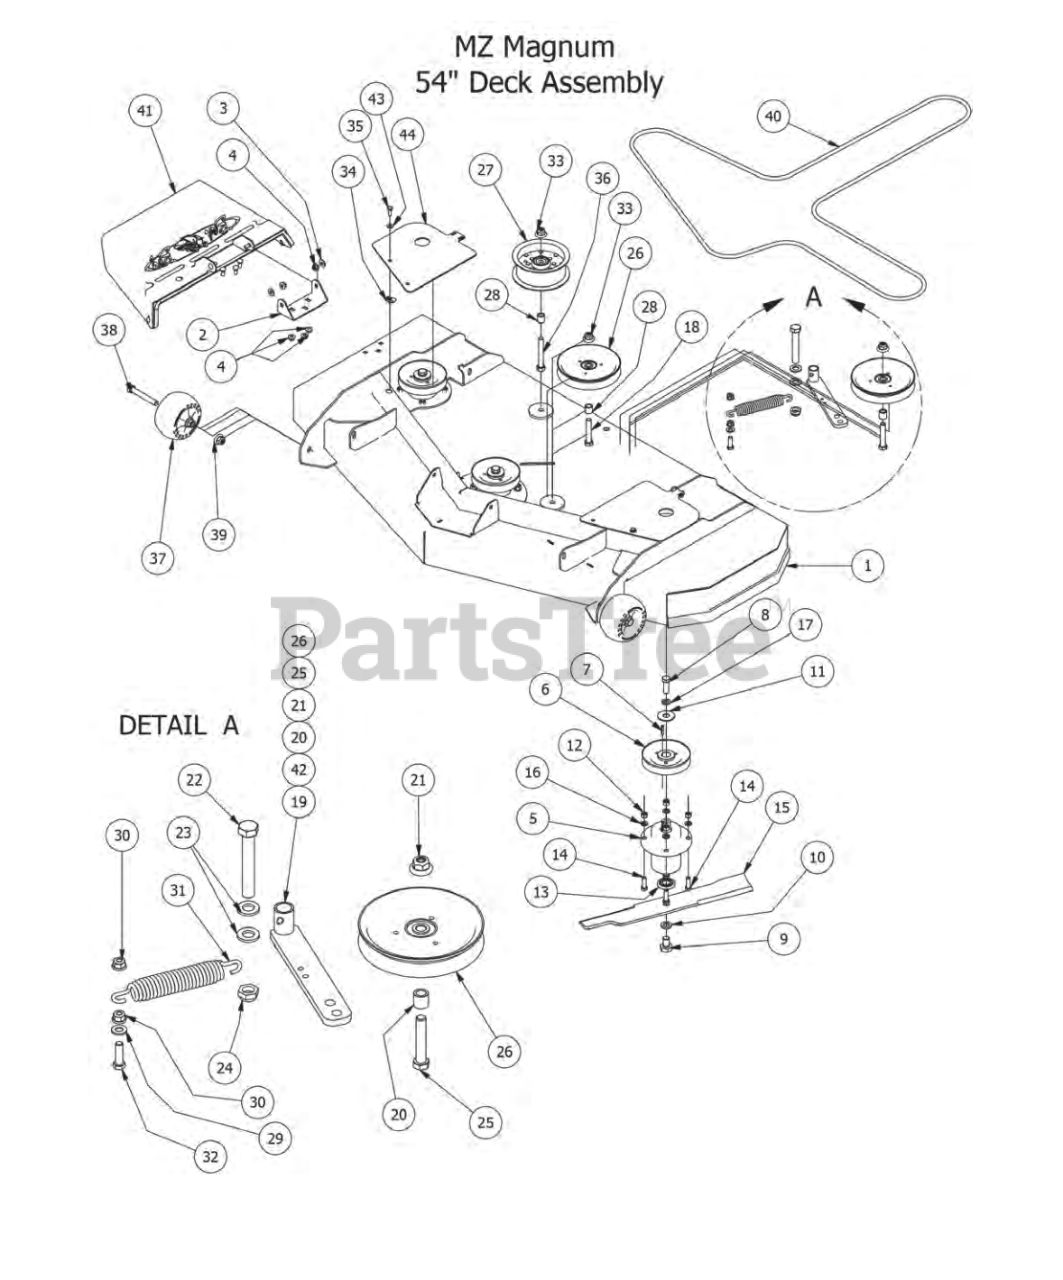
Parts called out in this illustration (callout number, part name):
1	54 MZ Deck
2	Chute Hanger 48 MZ
3	360 ID Plastic Washer
4	5/16" Nylon Flange Nut
6	MZ Deck Pulley
7	3/16 x 1 Square Key
8	1/2"-20 x 1 1/2 Grade 5 Fine Thread Bolt
9	5/8" x 1 1/2" Gr8 Hex Bolt (Fine)
10	5/8" Lock Washer
11	Type B Plain Washer
12	3/8" Hex Nut
13	Spindle Bearing
14	3/8" x 1 1/4" Hex Bolt
15	54" MZ Fusion Blade
16	3/8" Lock Washer
17	1/2" Lock Washer
18	1/2" x 2 3/4" Hex Bolt
19	Deck Idler 2009 AOS
20	3/4 OD x 1/2 ID x 3\4 Length
21	1/2-13 Nylon Flange Nut-Orange
22	5/8" x 4" Hex Bolt
23	.635 ID Plastic Washer
24	5/8-11 Nylon Insert Jam Half Nut
25	1/2" x 2 3/4" Hex Bolt
26	5-3/4 Idler Pulley
27	5 3/4 flat idler-32fI-92-008
28	3/4 OD x 1/2 ID x 3\4 Length
29	3/8" Flat Washer
30	3/8" Nylock Flange Nut
31	Deck Idler Spring 2009
32	3/8" x 1 1/4" Hex Bolt
33	1/2-13 Nylon Flange Nut-Orange
34	1/4-20 Cage Nut
35	1/4" Hex Bolt
36	1/2-13 x 3 1/2 GR 5 Hex Bolt
37	Deck Wheel
38	1/2 x 3 1/2 Flange Bolt Grade 8
39	1/2-13 Nylon Flange Nut-Orange
40	B 138 Belt 54" MZ Magnum
41	MZ Discharge Assembly
42	MZ Deck Idler Assembly (Components 19,20,21,25,26,43)
43	1/4" Flat Washer
44	2014 54" MZ Mag Pulley Cover
